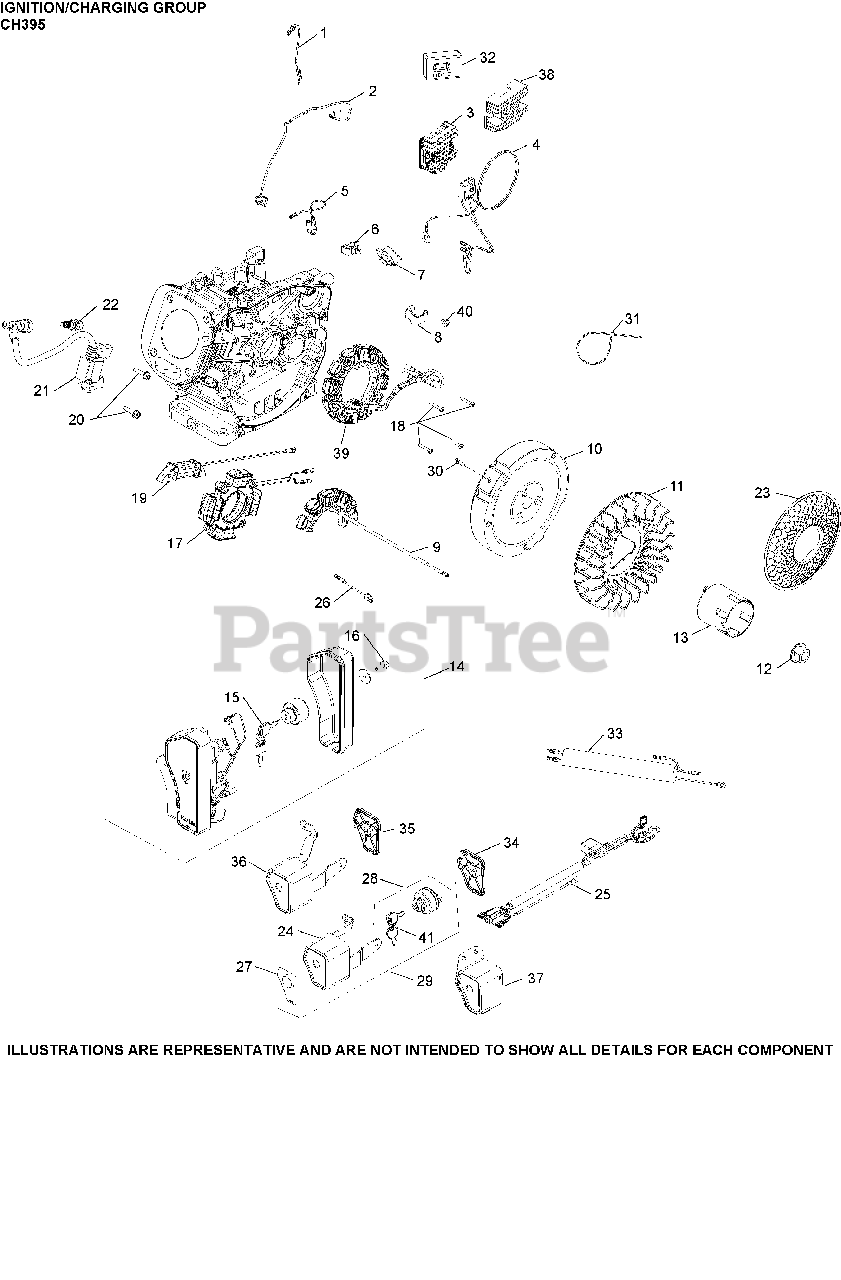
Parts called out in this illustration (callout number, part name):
2	LEAD, GROUND TO KILL
3	REGULATOR, 18 AMP
4	HARNESS, REGULATOR WIRING ASSY
8	BRACKET, STATOR WIRE
10	FLYWHEEL ASSY ELECTRIC START (CH395)
11	FAN, FLYWHEEL
12	NUT, FLYWHEEL
13	CUP, STARTER DRIVE
16	SCREW, HEX FLANGE (M6)-USE 25 086 433-S
18	SCREW, STATOR MOUNTING (CKY)
20	SCREW, M6 X 25 USE 25 086 436-S
21	MODULE, SPARK PLUG ASSY
22	SPARK PLUG
24	KEYBOX HOUSING
25	HARNESS, WIRING ASSEMBLY (18 AMP)
27	LABEL, KEY BOX
28	SWITCH, KEY ASSEMBLY
29	KIT, KEY BOX ASSEMBLY
34	COVER, KEY BOX
39	STATOR ASSEMBLY, 18A
40	SCREW, COIL BRACKET (CKY)
